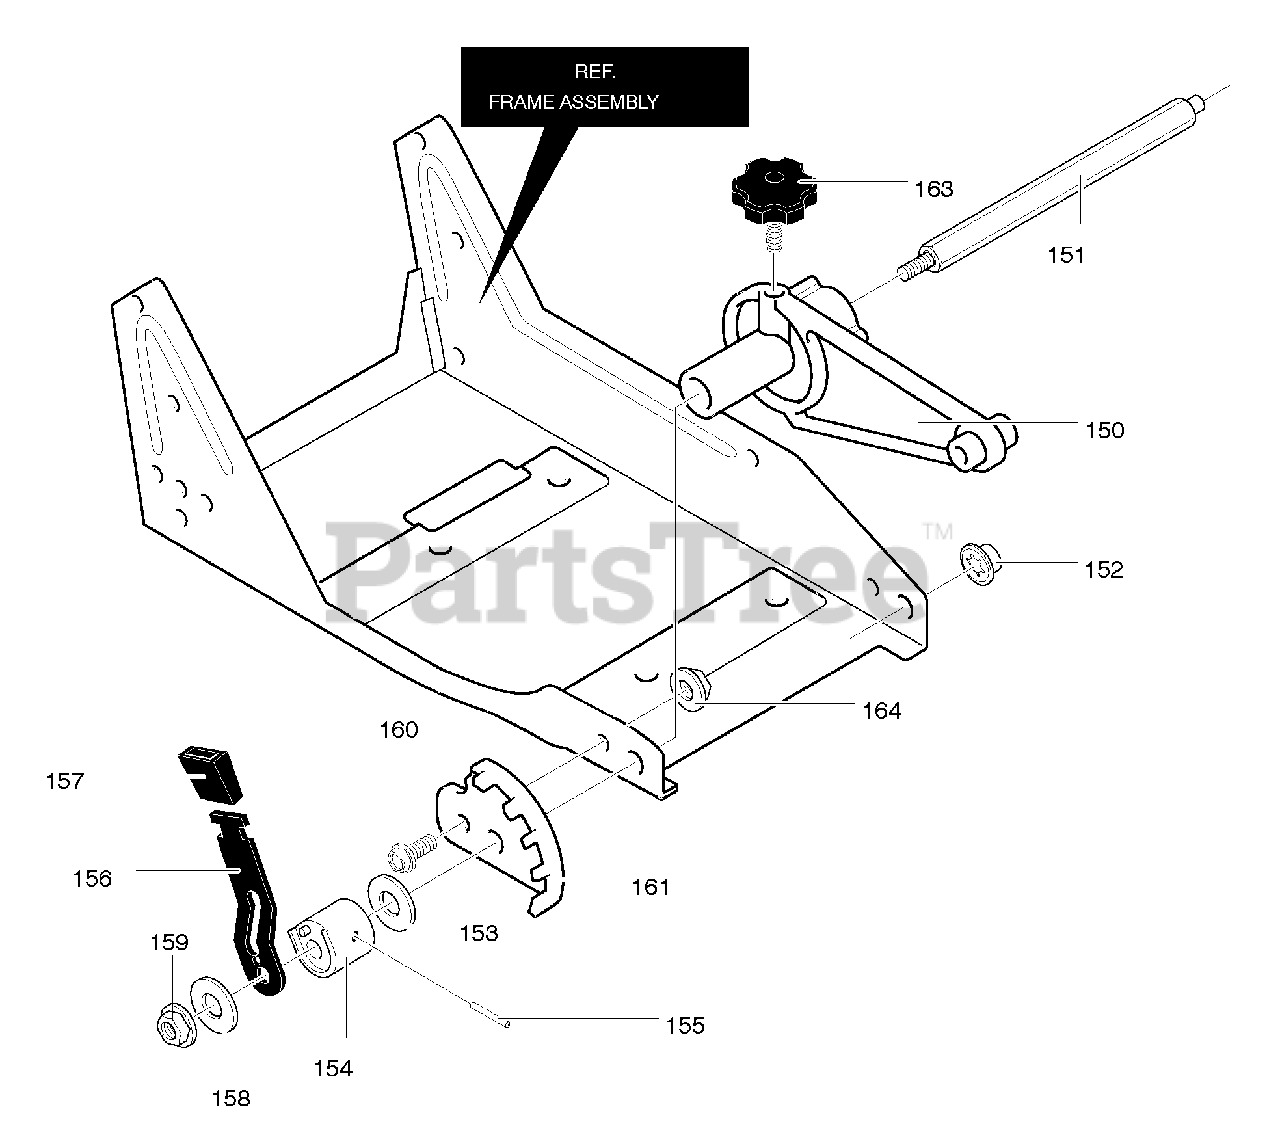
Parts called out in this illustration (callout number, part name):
150	Front Wheel Arm
151	Rod, Front Mount Curb
152	Pushnut, Washer
153	Plastic Washer
154	Spacer, Height Adjust
155	Pin, Spring
156	Lever, Height Adjust
157	Knob, Rectangle
158	Flatwasher
160	Screw, 5/16-18x.63
161	Plate, Height Adjust
163	Knob, Molded
164	Nut, 5/16-18
